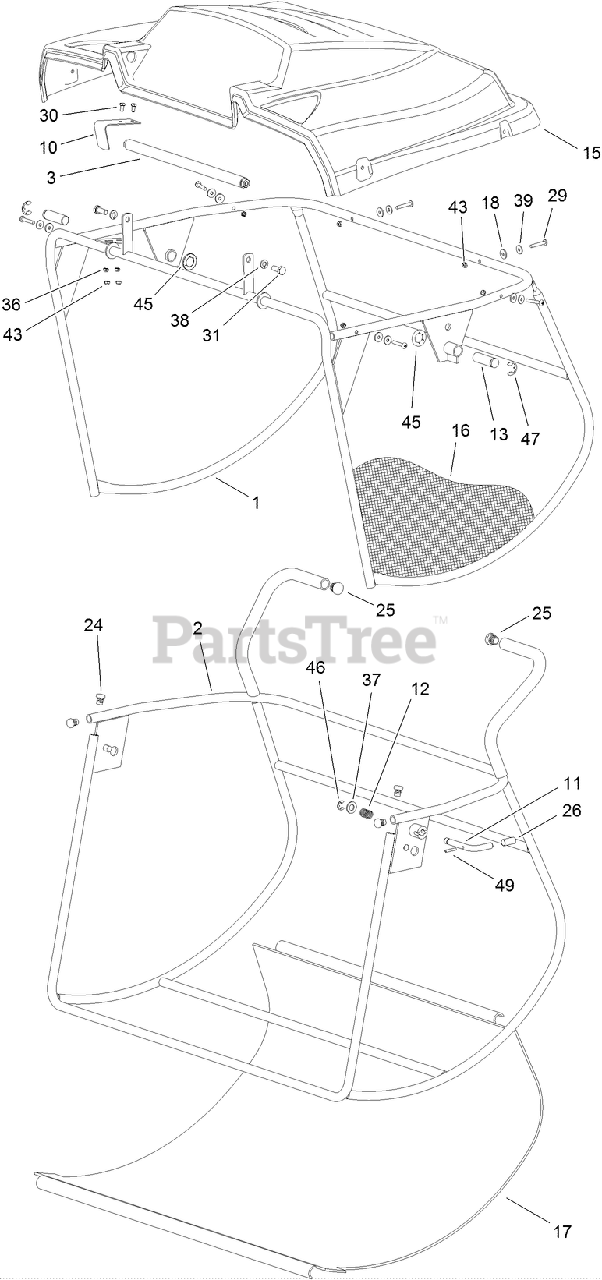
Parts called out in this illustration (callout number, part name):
1	UPPER FRAME ASM
2	LOWER FRAME ASM
3	HANDLE-LIFT
10	BRACKET-COLLECTOR, INTERLOCK
11	LEVER-COLLECTOR LOCK
12	SPRING
15	COVER-COLLECTOR
16	BAG-GRASS
17	BAG-LOWER
18	WASHER-RUBBER
31	SCREW-HH
36	WASHER
37	WASHER-FLAT
38	WASHER-SPRING
39	WASHER-FLAT
43	NUT-LOCK
45	RING-LOCK
46	E-CLIP
47	E-CLIP
